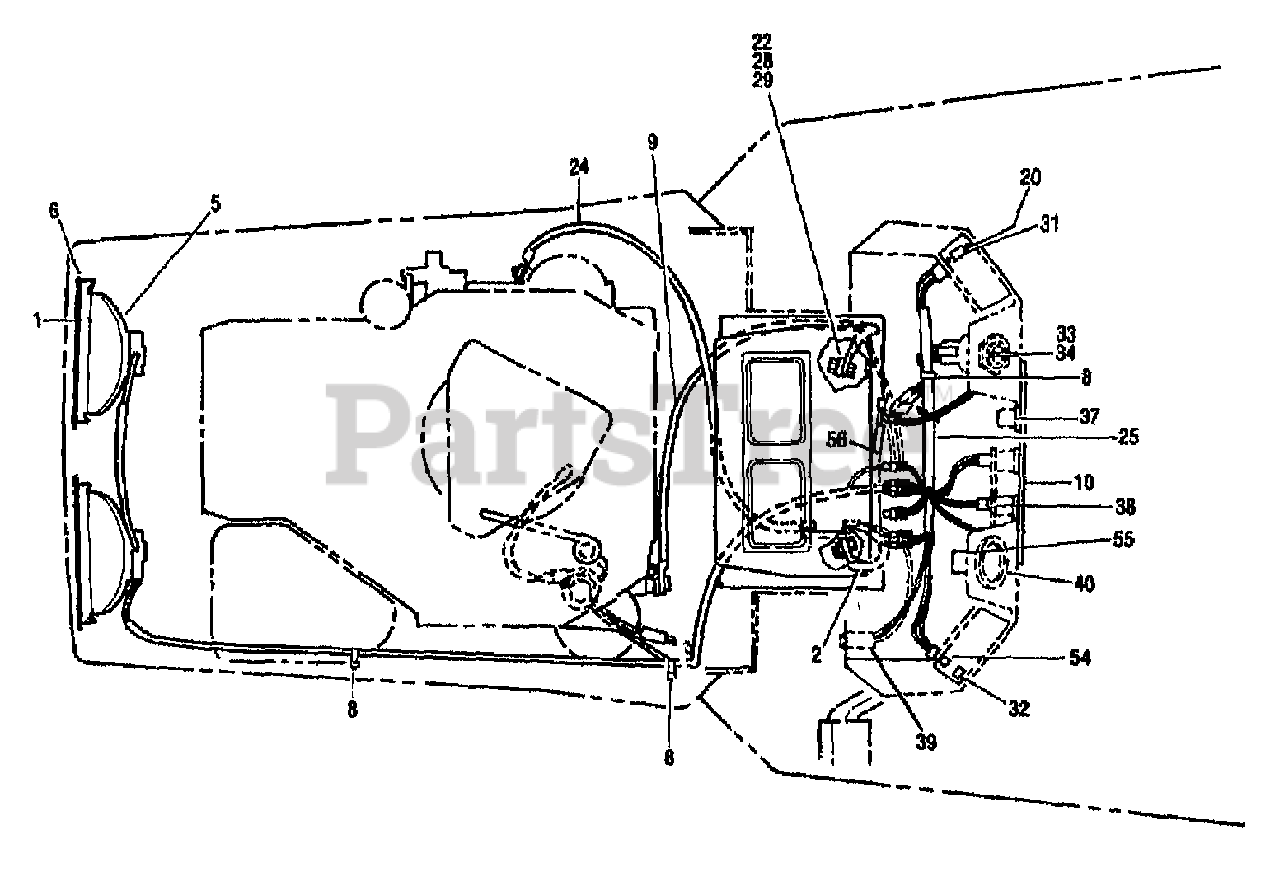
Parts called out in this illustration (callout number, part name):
2	CABLE-BATTERY (+)
5	ASSM-LIGHT
8	TIE-CABLE NYLON BLACK
9	CABLE (-)
20	SCR-FHP #6-32X.50 ZP
22	NUT-HEX 1/4-20 ZP
24	CABLE-STARTER
25	HARNESS-CONSOLE WIRING
28	WASHER-LK .25 ZP
29	SCR-HH 1/4-20X.625 G5 ZP
31	SWITCH-PTO
32	SWITCH-LIGHT
33	SWITCH-IGNITION
34	KEY-IGNITION
37	BULB (MFG NO. GE 73)
38	SCR-PHP M6-32X.38 ZP
39	FUSE-30 AMP
40	METER-HOUR
54	SWITCH-SPEED CONTROL
55	RELAY-SPEED CONTROL
56	HARNESS-CRUISE
